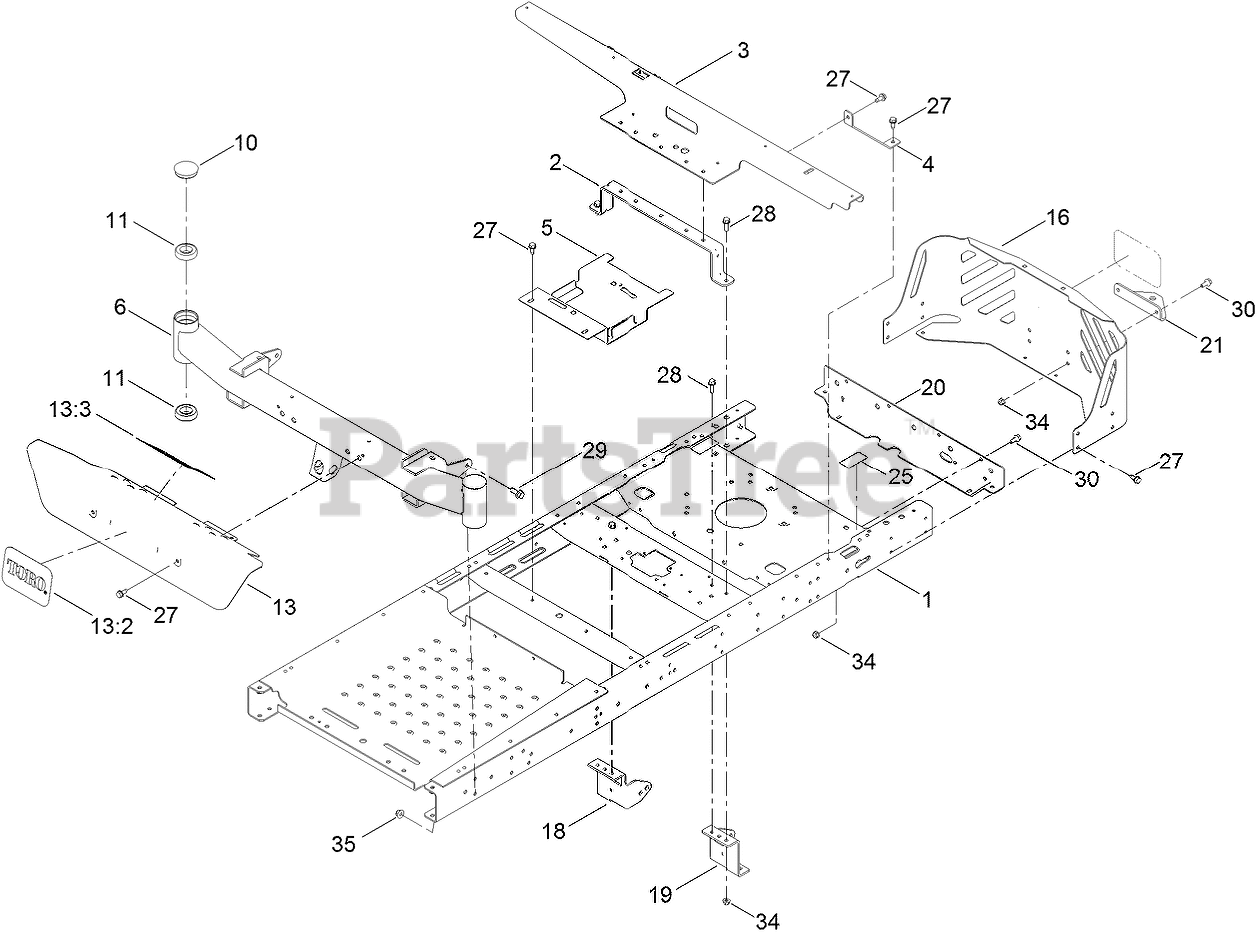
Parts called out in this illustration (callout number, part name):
1	RIVETED FRAME ASM (WIDE LEVER)
2	BRACE-SEAT, REAR (WIDE)
3	SUPPORT-POD, WIDE
4	SUPPORT-TANK, REAR
5	BRACKET-BATTERY
6	AXLE-WIDE
10	CAP-GREASE
11	BEARING-BALL
13	FOOTREST ASM
13:2	DECAL
13:3	DECAL-DANGER
16	GUARD-ENGINE, WIDE
18	MOUNT-HYDRO, FRONT (RIGHT)
19	MOUNT-HYDRO, FRONT (LEFT)
20	CROSSMEMBER-REAR, WIDE
21	BRACKET-HITCH
25	DECAL-BYPASS
27	SCREW-HWHTF
28	SCREW-HHF
29	SCREW-HHF
30	SCREW-HHF
34	NUT-HF, NI
35	NUT-HF, NI
